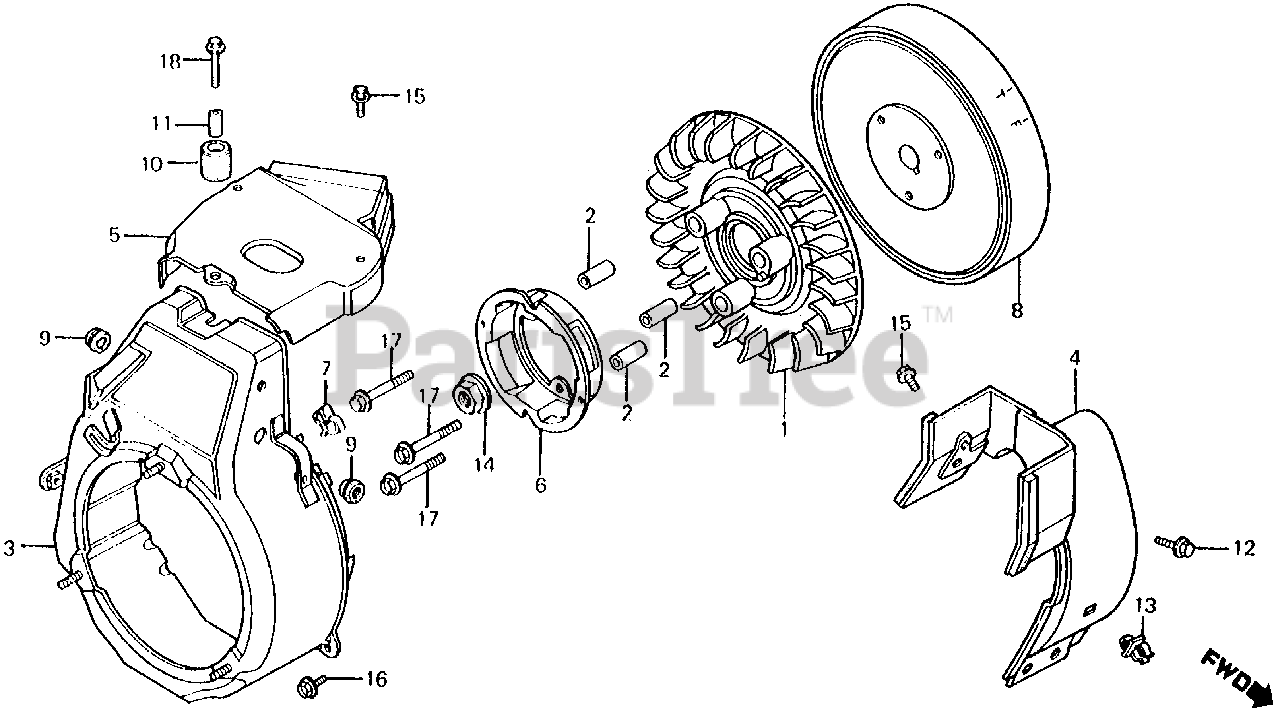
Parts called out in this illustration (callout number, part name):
1	FAN, COOLING
2	COLLAR, FAN
3	COVER, FAN
5	COVER, TOP
6	PULLEY, STARTER
7	CLIP, IGNITION WIRE (8MM)
8	FLYWHEEL (C.D.I.)
9	GROMMET, WIRE (NOT AVAILABLE)
10	RUBBER, STOPPER
11	COLLAR, TAILLIGHT SETTING
12	BOLT, FLANGE (6X12) (CT200)
13	CLIP, HOSE
13	CLIP, ROD HOLDER
14	NUT, FLANGE (12MM)
15	BOLT, FLANGE (6X10)
16	BOLT, FLANGE (6X12)
17	BOLT, FLANGE (6X32)
18	BOLT, FLANGE (6X20)
